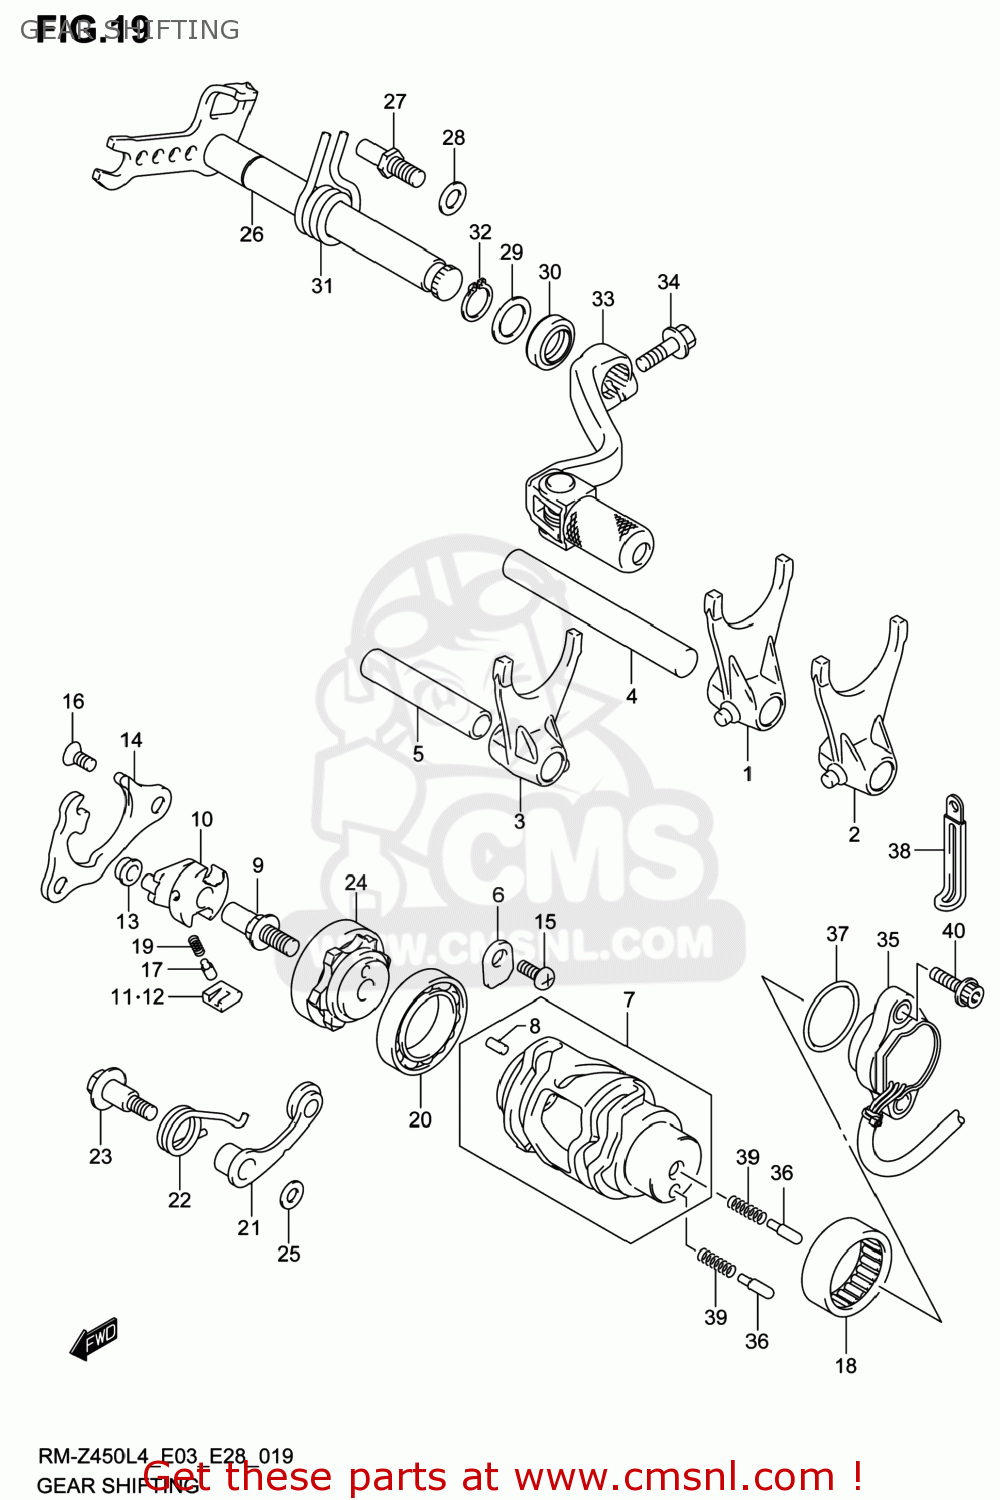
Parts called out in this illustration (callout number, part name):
1	FORK,GEAR SHIFT NO.1
2	FORK,GEAR SHIFT NO.2
3	FORK,GEAR SHIFT NO.3
4	SHAFT,GEAR SHIFT FORK NO.1
5	SHAFT,GEAR SHIFT FORK(L:60)
6	RETAINER
7	CAM,GEAR SHIFT
8	PIN
9	PIN,GEAR SHIFT CAM
10	SHIFTER,GEAR SHIFT CAM
11	PAWL,GEAR SHIFT NO.1
12	PAWL,GEAR SHIFT NO.2
13	ROLLER,GEAR SHIFT CAM SHIFTER
14	LIFTER,GEAR SHIFT PAWL
15	SCREW(6X12)
16	SCREW(6X12)
17	PIN
18	BEARING(25X32X12)
19	SPRING
20	BEARING
21	STOPPER,GEAR SHIFT CAM
22	SPRING,GEAR SHIFT CAM STOPPER
23	BOLT,SHIFT CAM STOPPER
24	PLATE,GEAR SHIFT CAM STOPPER
25	WASHER
26	SHAFT,GEAR SHIFT
27	STOPPER,GEAR SHIFT ARM
28	SHIM(8.8X14X1)
29	SHIM(14X20X1)
30	SEAL,OIL(14X22X7.3)
31	SPRING
32	CIRCLIP
33	LEVER ASSY,GEAR SHIFT
34	BOLT
35	BASE ASSY,GEAR SHIFT TERMINAL
36	PIN(5X15.5)
37	O RING(D:2.4,ID:26.2)
38	CLAMP(L:45)
39	SPRING
40	BOLT
